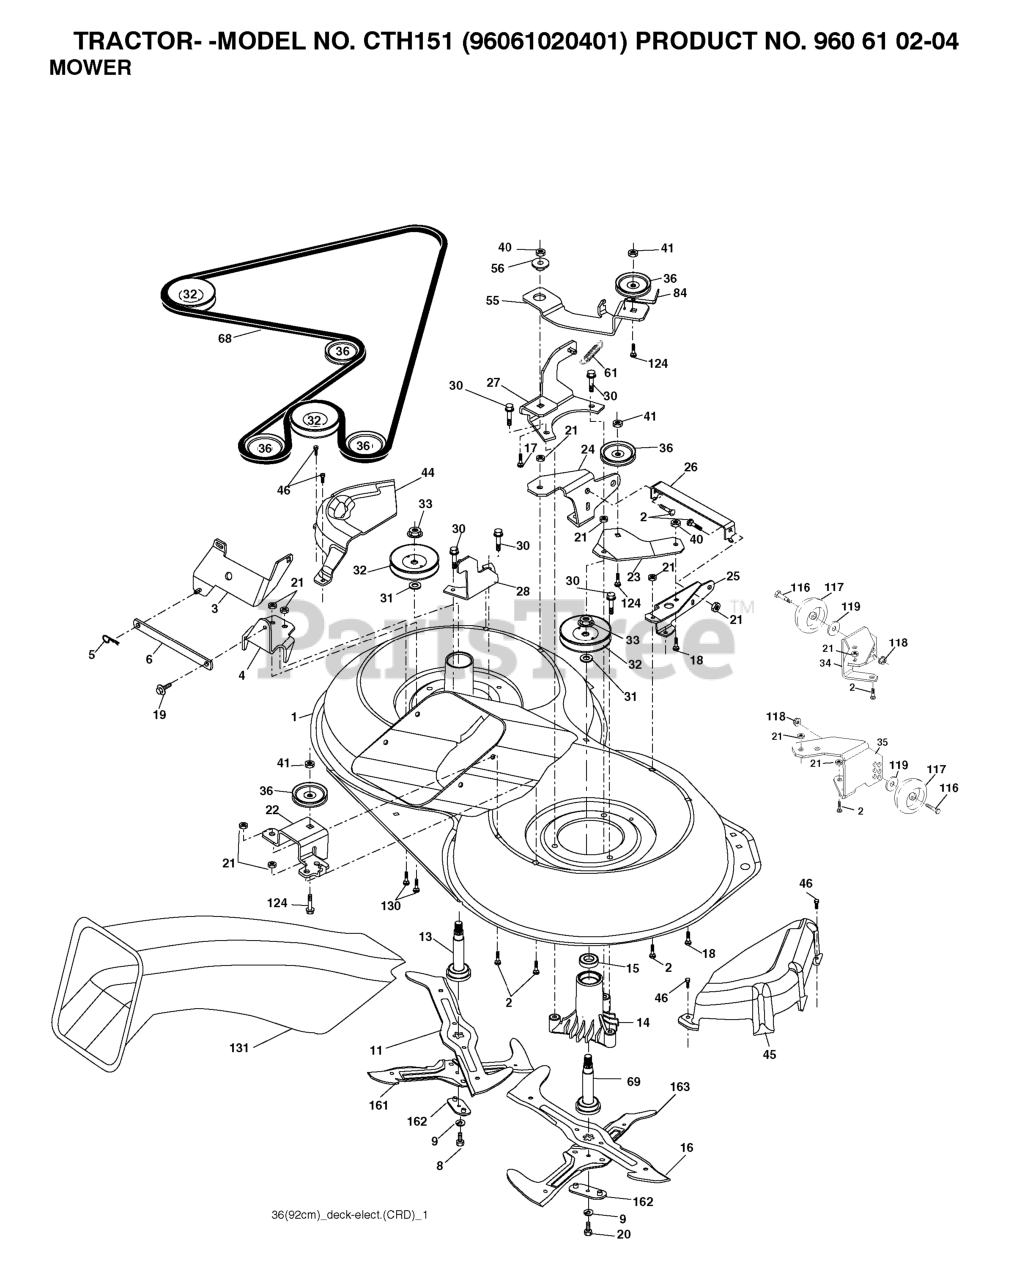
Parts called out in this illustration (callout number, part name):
2	RP BOLT 5/16-18 X3/4 ZN/YEL GR
5	RETAINER-SPRNG RB
6	BAR.SWAY.92.CRD
8	BOLT.3/8-24X1.25 GR8
9	LOCKWASHER
13	SHAFT ASM VENT
14	HOUSING.MANDREL.VENTED (MACHD)
17	BOLT.3/8-14X1.25
19	BOLT SHD 5/16-18
20	BOLT.3/8-24X1.25GR8. LHTHRD
21	LOCKNUT
26	SUPPORT
30	SCREW, WASHER HEAD
31	WASHER.SPACER.MANDREL
33	NUT.FLANGE.LOCK.TOP
36	PULLEY.IDLER.4.25
41	NUT LOCK FLG 3/8-16 UNC
45	COVER.MANDREL.RH.CRD
46	SCREW.1/4-20X5/8
55	ARM.IDLER.92 CRD.2006
56	SPACER.RETAINER.MOWER
61	SPRING
68	BELT.DRIVE.92CM.CRD.2006
69	SHAFT.ASM.W/LWR.BRG.RH.THREAD
84	KEEPER, BELT IDLER
116	BOLT.SHOULDER.3/8-16X3-5/8.
117	RP WHEEL. GUAGE RALLY
118	NUT LOCK FLG 3/8-16 UNC
119	WASHER
124	BOLT.3/8-16X1.50
130	BOLT.CARR.SQNK.5/16-18UNC.X3/4
131	CHUTE BAGGER
